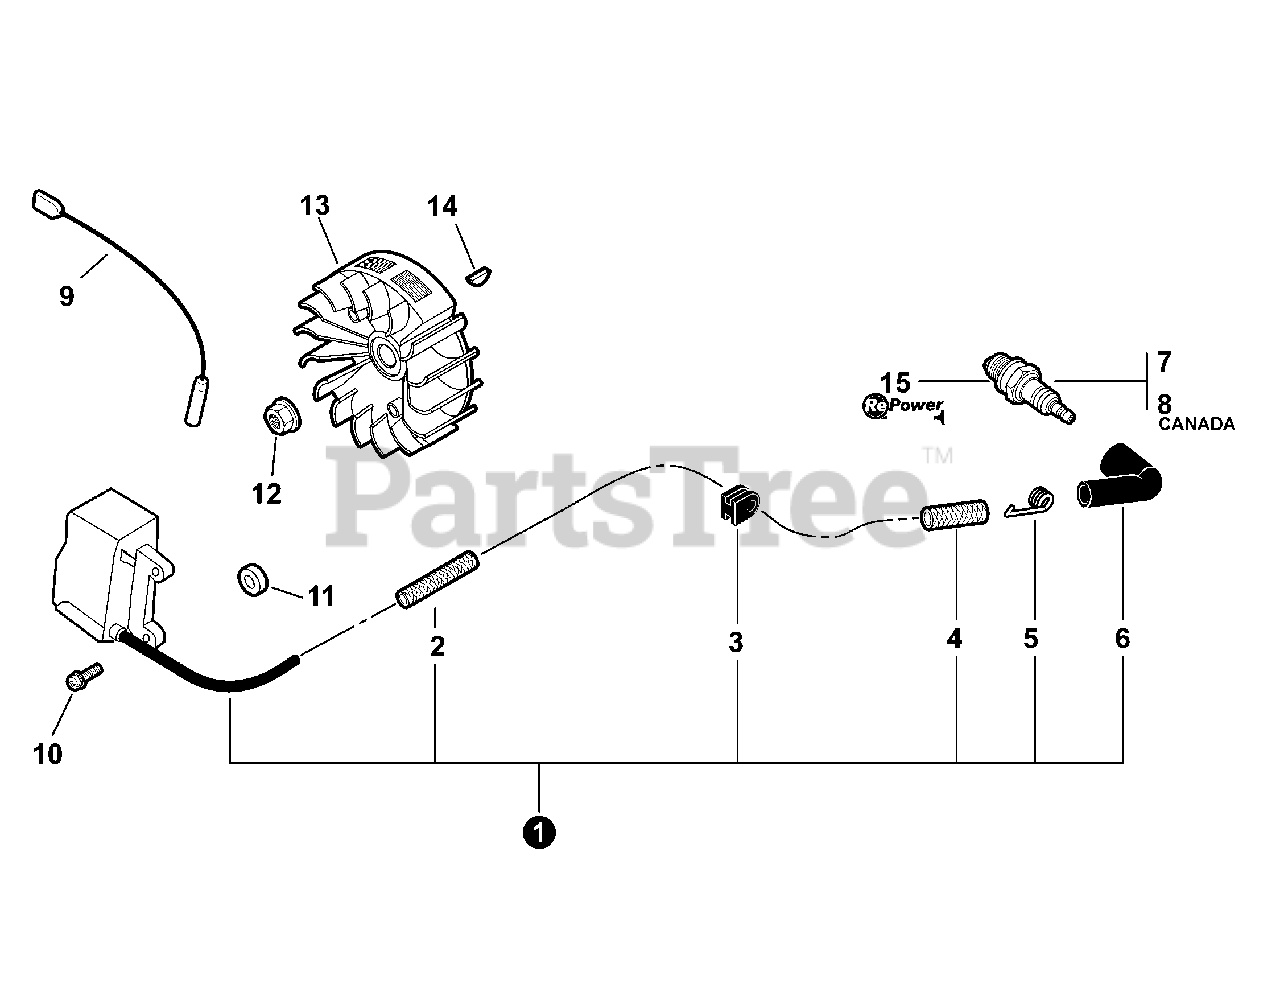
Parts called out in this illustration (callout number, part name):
1	COIL, IGNITION
2	TUBE, INSULATOR
4	TUBE, INSULATOR
5	TERMINAL, SPARK PLUG
6	CAP, SPARK PLUG
7	SPARK PLUG - BPM8Y
8	SPARK PLUG - BPMR8Y
9	LEAD - IGNITION
10	SCREW 5×22
11	WASHER 5.2×12×3
12	NUT, FLANGE M8
13	FLYWHEEL
14	KEY, WOODRUFF
15	TUNE-UP KIT - REPOWER
